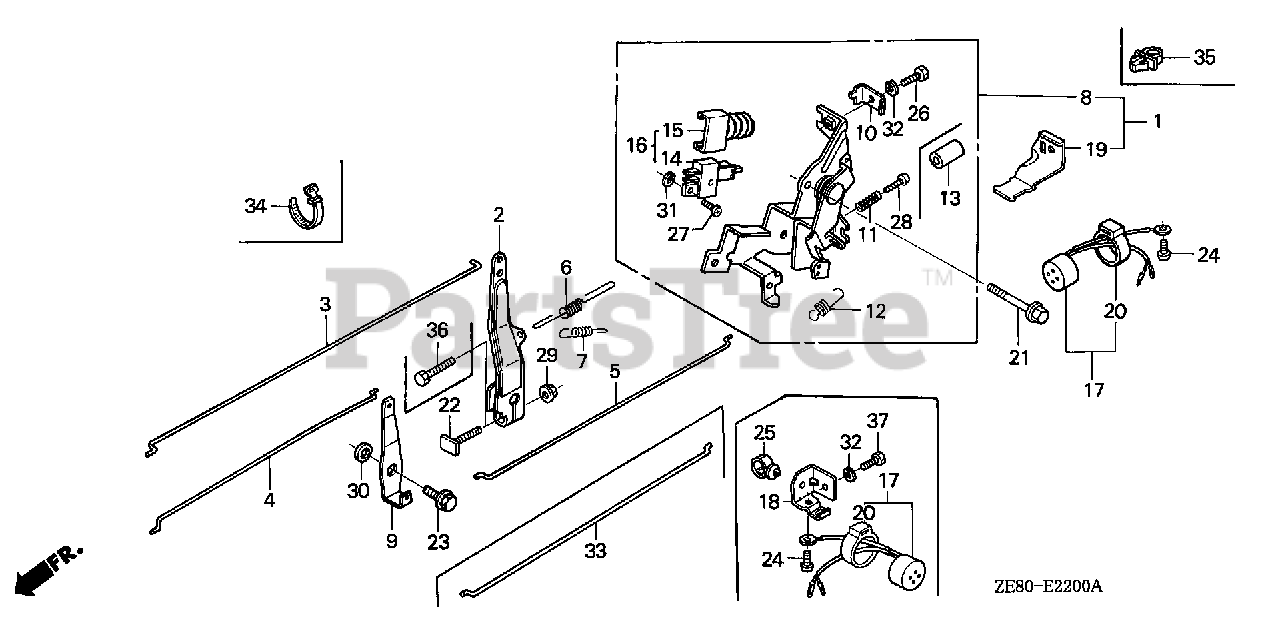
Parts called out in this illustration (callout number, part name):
2	ARM, GOVERNOR (NOT AVAILABLE)
3	ROD, GOVERNOR
4	ROD, CHOKE
5	ROD, JOINT
6	SPRING, GOVERNOR
7	SPRING, GOVERNOR PRIMARY
8	CONTROL ASSY.
8	CONTROL ASSY. (NOT AVAILABLE)
9	LEVER, CHOKE JOINT (NOT AVAILABLE)
10	HOLDER, CABLE
11	SPRING, CONTROL ADJUSTING
12	SPRING, CABLE RETURN
14	SWITCH ASSY., ENGINE
16	SWITCH ASSY., ENGINE STOP
17	BUZZER ASSY.
18	STAY, BUZZER
19	STAY, BUZZER
20	SUSPENSION, AUDIBLE PILOT
21	BOLT, FLANGE (6X12) (CT200)
22	BOLT, GOVERNOR ARM
23	BOLT, FLANGE (6MM)
24	SCREW, TAPPING (5X8)
25	CLIP, WIRE HARNESS (25MM)
25	CLIP, HARNESS
26	BOLT, RECESSED (5X16)
27	SCREW, PAN (4X14)
28	SCREW, PAN (5X20)
29	NUT, FLANGE (6MM)
30	WASHER, PLAIN (6MM)
31	WASHER, SPRING (4MM)
32	WASHER, SPRING (5MM)
34	BAND B1, WIRE
37	BOLT, RECESSED (5X16)
